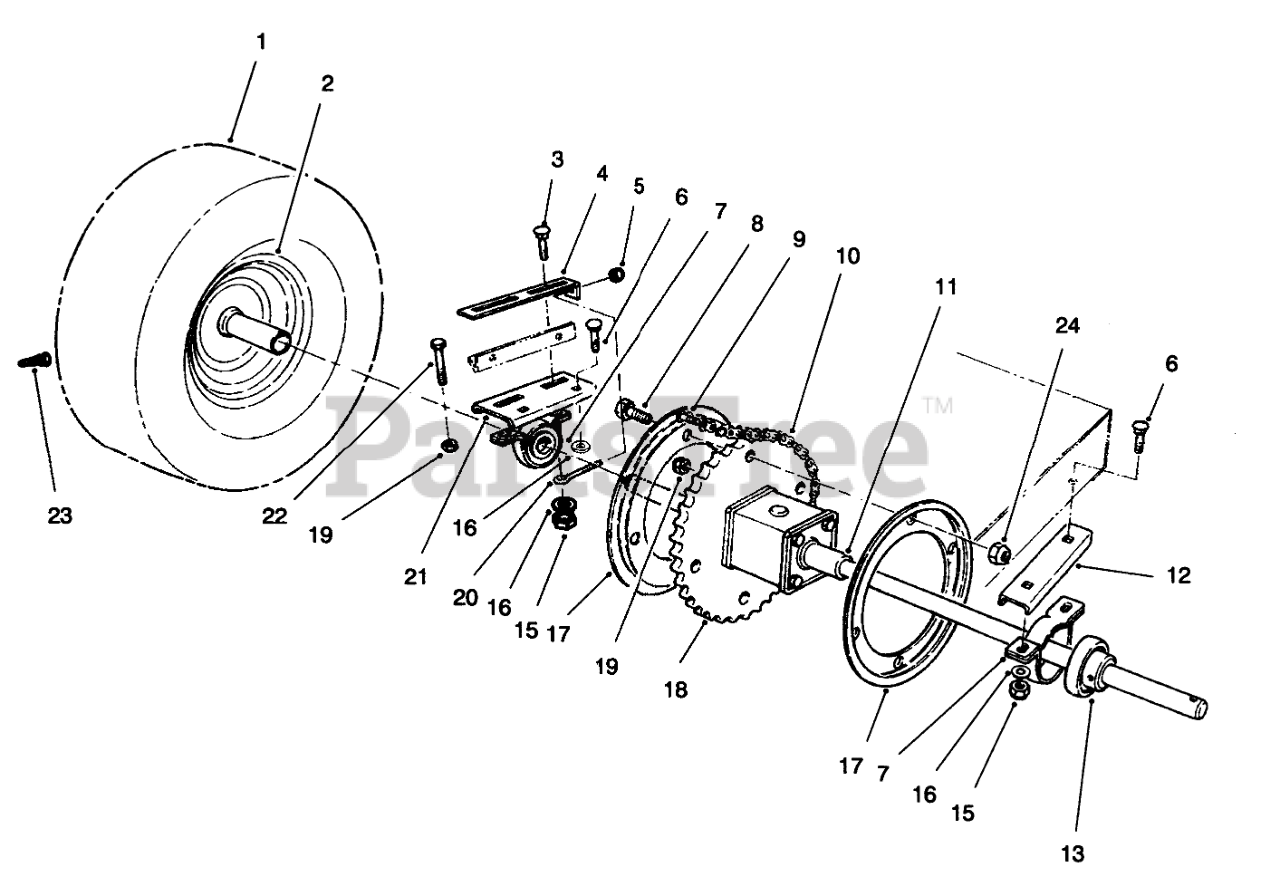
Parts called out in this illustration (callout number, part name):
1	TIRE,PNEU.13X5.00X6
2	WHEEL-REAR
3	SCREW-CARR
4	PLATE-ADJUSTING
5	NUT-LOCK, NI
6	BOLT-CARR
7	RTNR-PILLOW BLK
8	SCREW-HH
9	LINK-CHAIN
10	Chain (Incl. Ref. #9)
11	DIFFERENTIAL
12	LH AXLE SUPPORT (BLACK)
13	Bearing (Incl. Ref. #14)
15	NUT-LOCK, NI
16	WASHER-FLAT
17	GUIDE-REAR CHAIN
18	SPROCKET
19	NUT-LOCK, NI
20	SCREW-ADJUSTING
21	RH AXLE SUPPORT (BLACK)
22	AXLE MTG BOLT
23	STEM-VALVE
24	NUT-HEX
